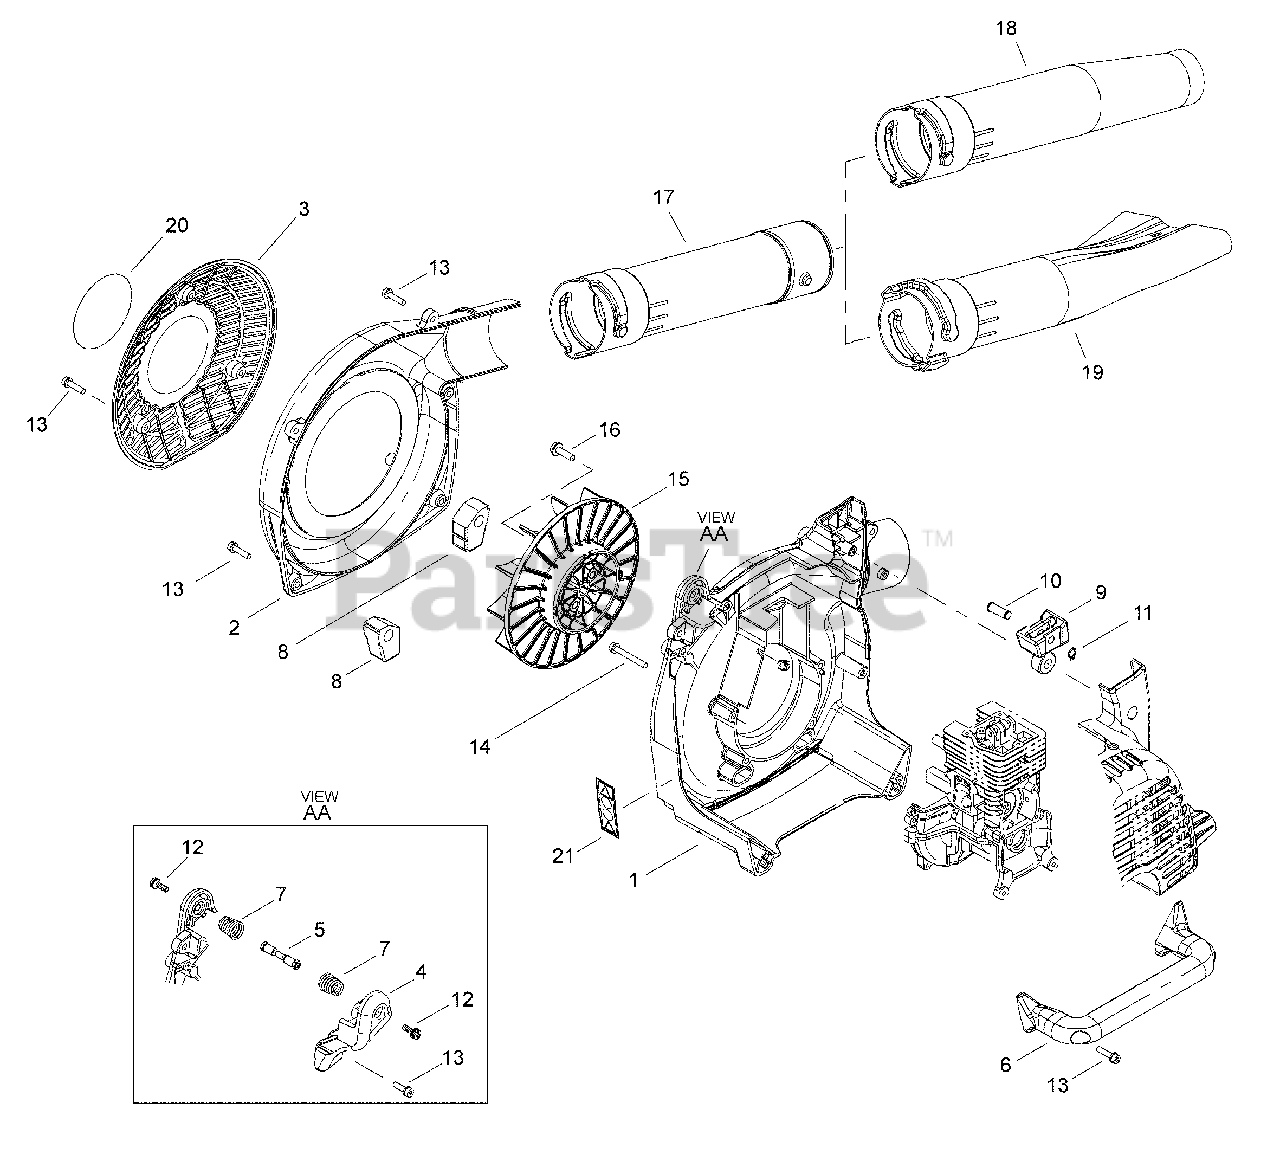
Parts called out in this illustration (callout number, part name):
1	CASE, FAN
2	COVER, FAN - LEFT
3	COVER, INTAKE
4	MOUNT, HANDLE
5	NUT, HANDLE 5
6	HANDLE, SIDE
7	SPRING, COIL Ø18ר14
8	CUSHION
9	CUSHION, AV
10	PIN, LOCK
11	RING, SNAP 8 MM
12	SCREW, ADHESIVE M5×16
13	BOLT M5×20
14	BOLT M5×40
15	FAN
16	BOLT M6×20
17	TUBE, BLOWER
18	TUBE, BLOWER - ROUND NOZZLE
19	NOZZLE, FAN TIP
20	LABEL, EB2510
21	LABEL, CAUTION
